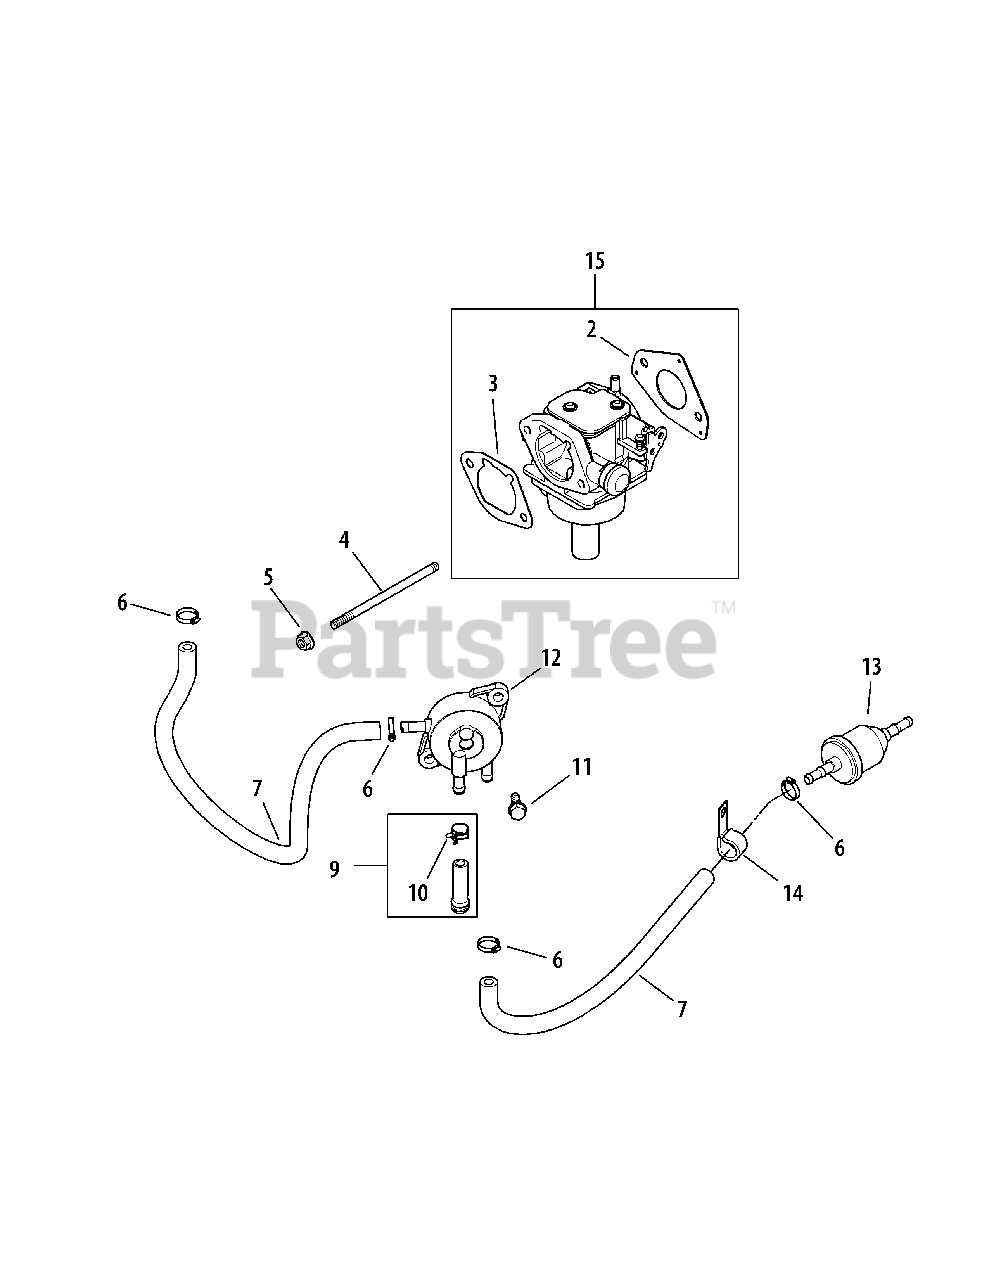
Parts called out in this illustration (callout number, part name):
2	Carburetor Gasket
3	Air Cleaner Base Gasket
4	Stud, M6 X 1.0 X 106
5	Flg. Nut, M6 X 1.0
6	Hose Clamp, 1/2
11	Tap Screw, M6 X 1.7 X 18
15	Carburetor Kit, 19mm (Inc. 2 & 3)
